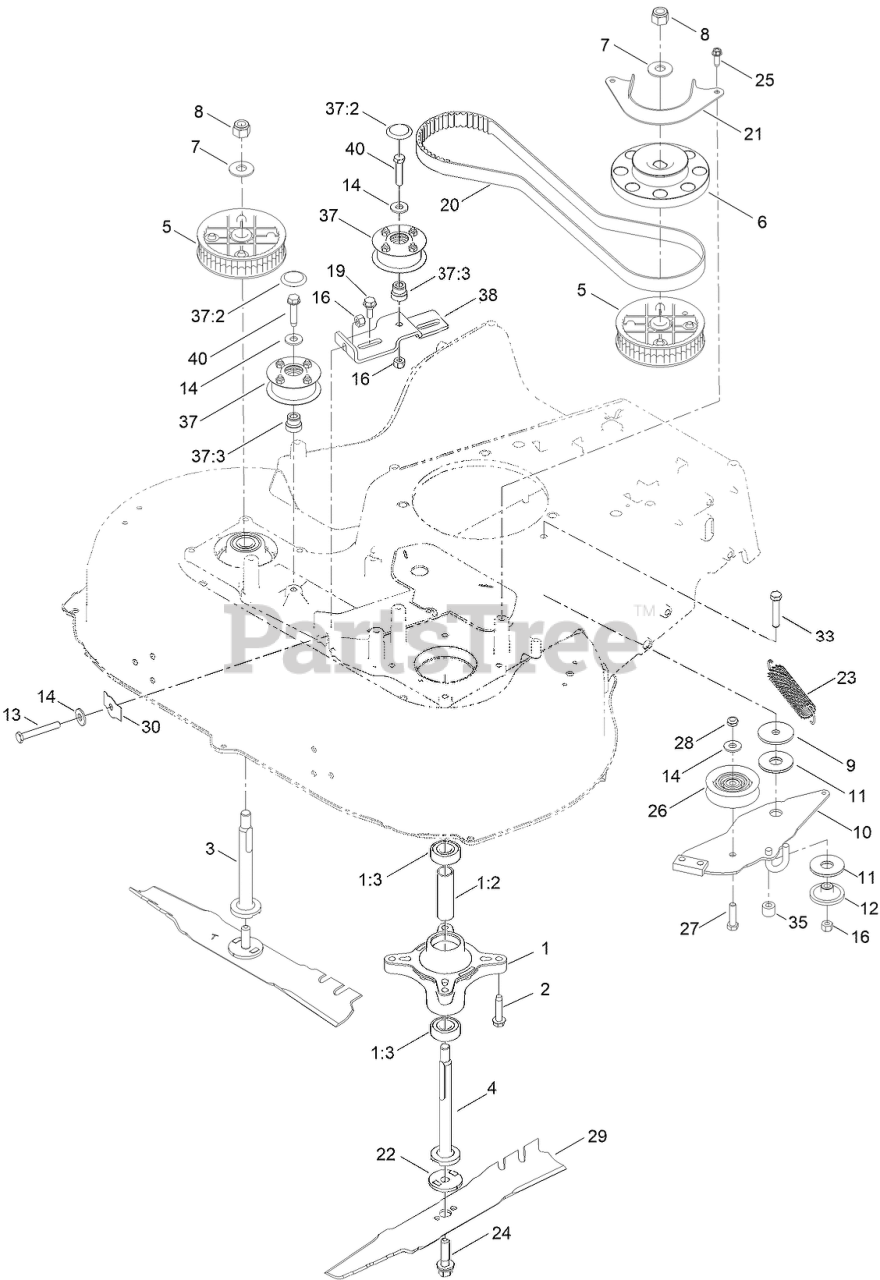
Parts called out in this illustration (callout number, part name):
1	SPINDLE ASM
1:2	SPACER
1:3	BEARING-BALL
2	SCREW-THD ROLL, HWH
3	SHAFT-SPINDLE
4	SHAFT-SPINDLE
5	SPROCKET
6	PULLEY-BRAKE, SPINDLE
7	WASHER-SPRING
8	NUT-HEX
9	WASHER-REBOUND
10	BRAKE ARM ASM
11	WASHER-FRICTION, COMPOSITE
12	SPACER
13	BOLT-TAP, HH
14	WASHER-FLAT
16	NUT-LOCK, NI
19	SCREW-SHOULDER,HWH
20	BELT-SYNCHRONOUS
21	GUIDE-BELT, SPINDLE
22	ADAPTER-BLADE
23	SPRING-EXTENSION, BRAKE
24	BOLT-BLADE
25	SCREW-HWHTF
26	PULLEY-IDLER
27	SCREW-HH
28	NUT-LOCK, NI
29	BLADE-ROTARY
30	SPRING-FLAT
33	SCREW-HH
35	HOSE-COOLANT
37	PULLEYS AND IDLER KIT
37:2	PLUG-BUTTON
37:3	ADAPTER-BORE
38	BRACKET-IDLER
